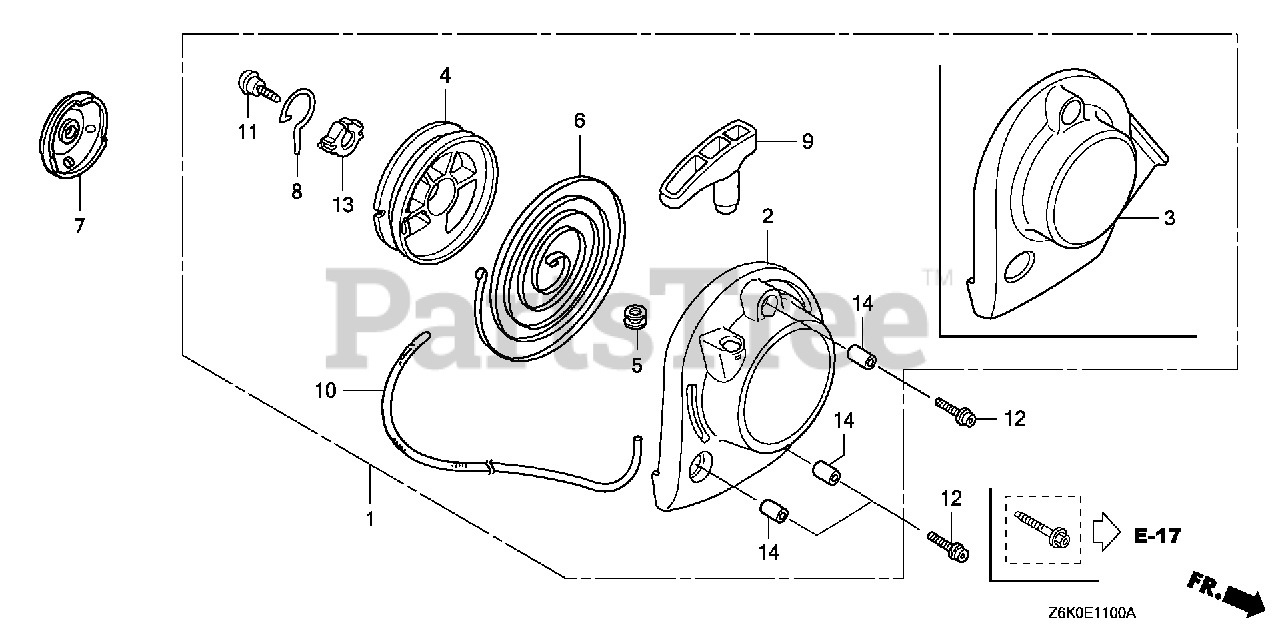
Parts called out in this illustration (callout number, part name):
1	STARTER ASSY., RECOIL
3	CASE, RECOIL STARTER
4	REEL, RECOIL STARTER
5	GUIDE, ROPE
6	SPRING, RECOIL STARTER
7	PULLEY, RECOIL STARTER
9	KNOB, RECOIL STARTER
10	ROPE, RECOIL STARTER
11	SCREW, SETTING
12	BOLT, SOCKET (5X16)
14	COLLAR A, HEAD COVER
